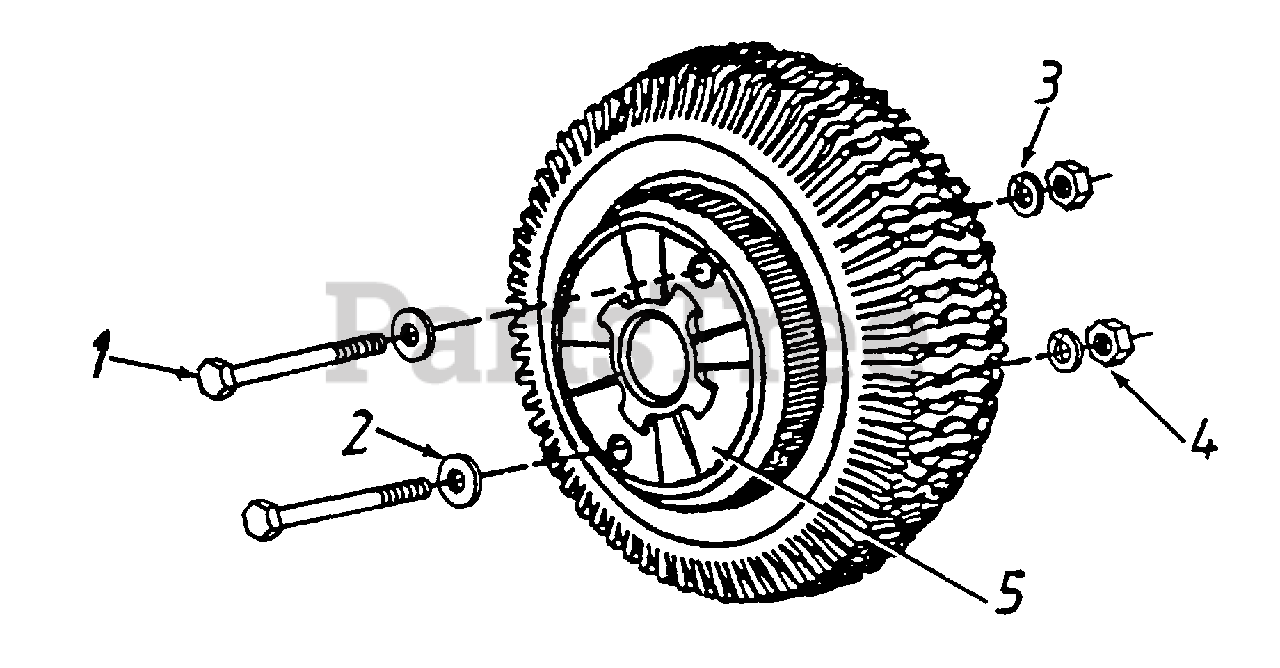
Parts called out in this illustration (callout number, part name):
1	Hex Bolt 3/8-16 x 7-1/2" Lg.
2	Fl-Wash. 3/8" I.D.
3	L-Wash. 3/8" I.D.
4	Hex Nut 3/8-16 Thread
5	31 Lb. Wheel Weights
